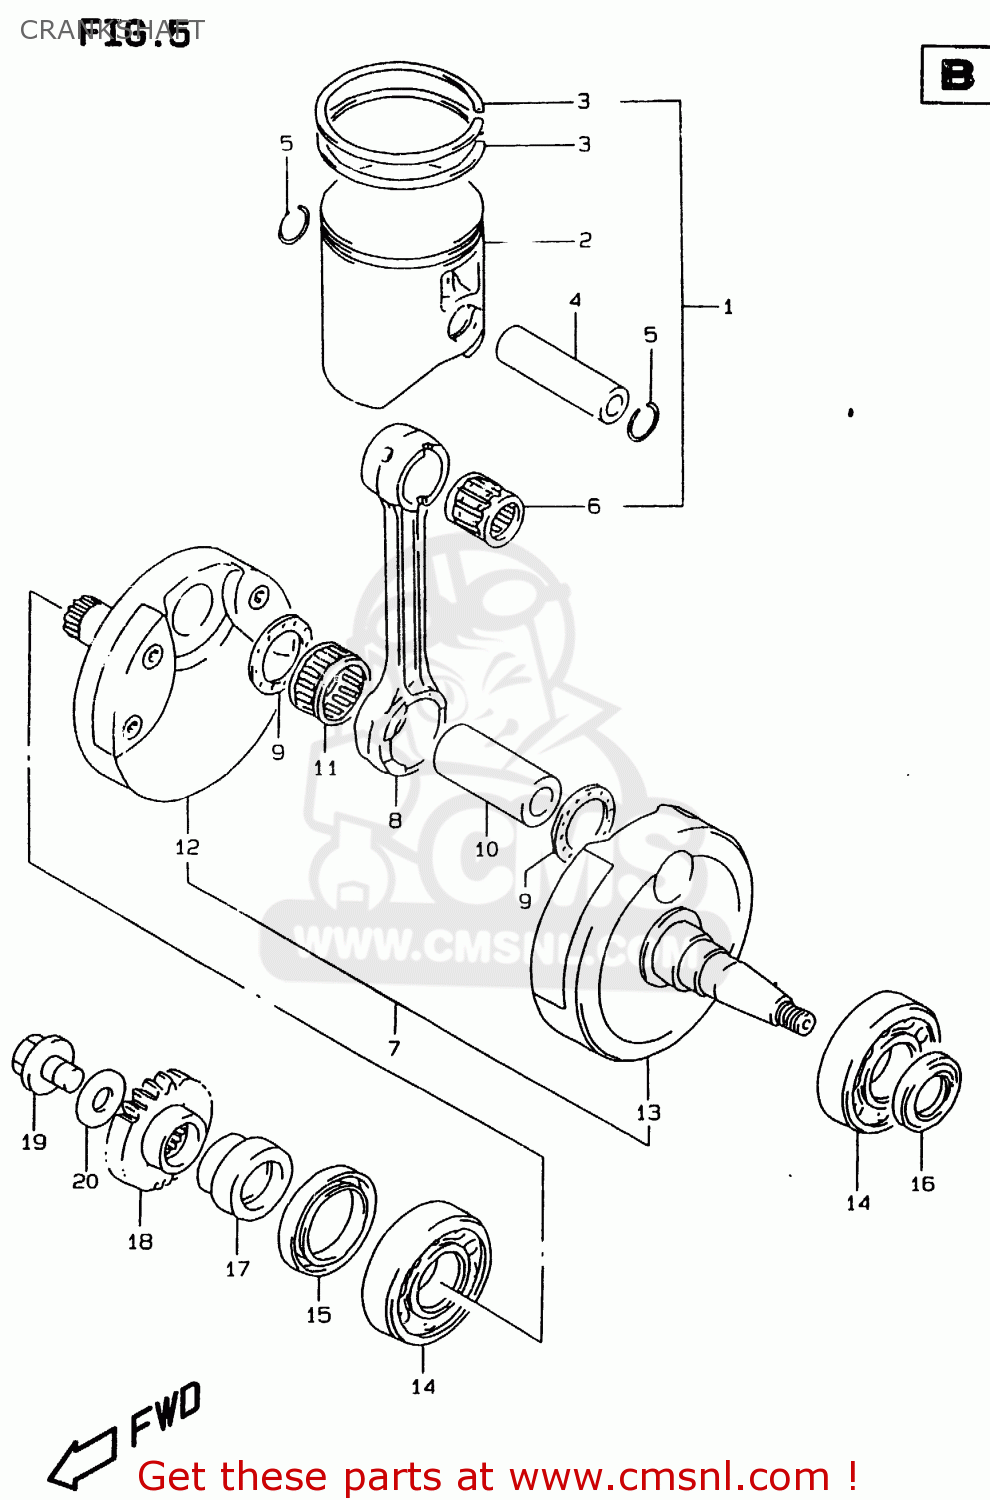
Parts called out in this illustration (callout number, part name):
1	PISTON KIT
2	PISTON
3	RING,PISTON
4	PIN,PISTON
5	CIRCLIP,PISTON PIN
6	BEARING(18X23X22)
7	CRANKSHAFT ASSEMBLY
8	ROD,CONNECTING
9	WASHER(24X38.5X1.5)
10	PIN,CRANK
11	BEARING(24X30X20)
12	CRANKSHAFT,R
13	CRANKSHAFT COMP,LEFT
14	BEARING(28X68X18)
15	SEAL,OIL(38X52X8)
16	SEAL,OIL(25X37X6)
17	SPACER,PRIMARY DRIVE GEAR
18	GEAR,PRIMARY DRIVE
19	BOLT,PRIMARY DRIVE GEAR
20	WASHER
